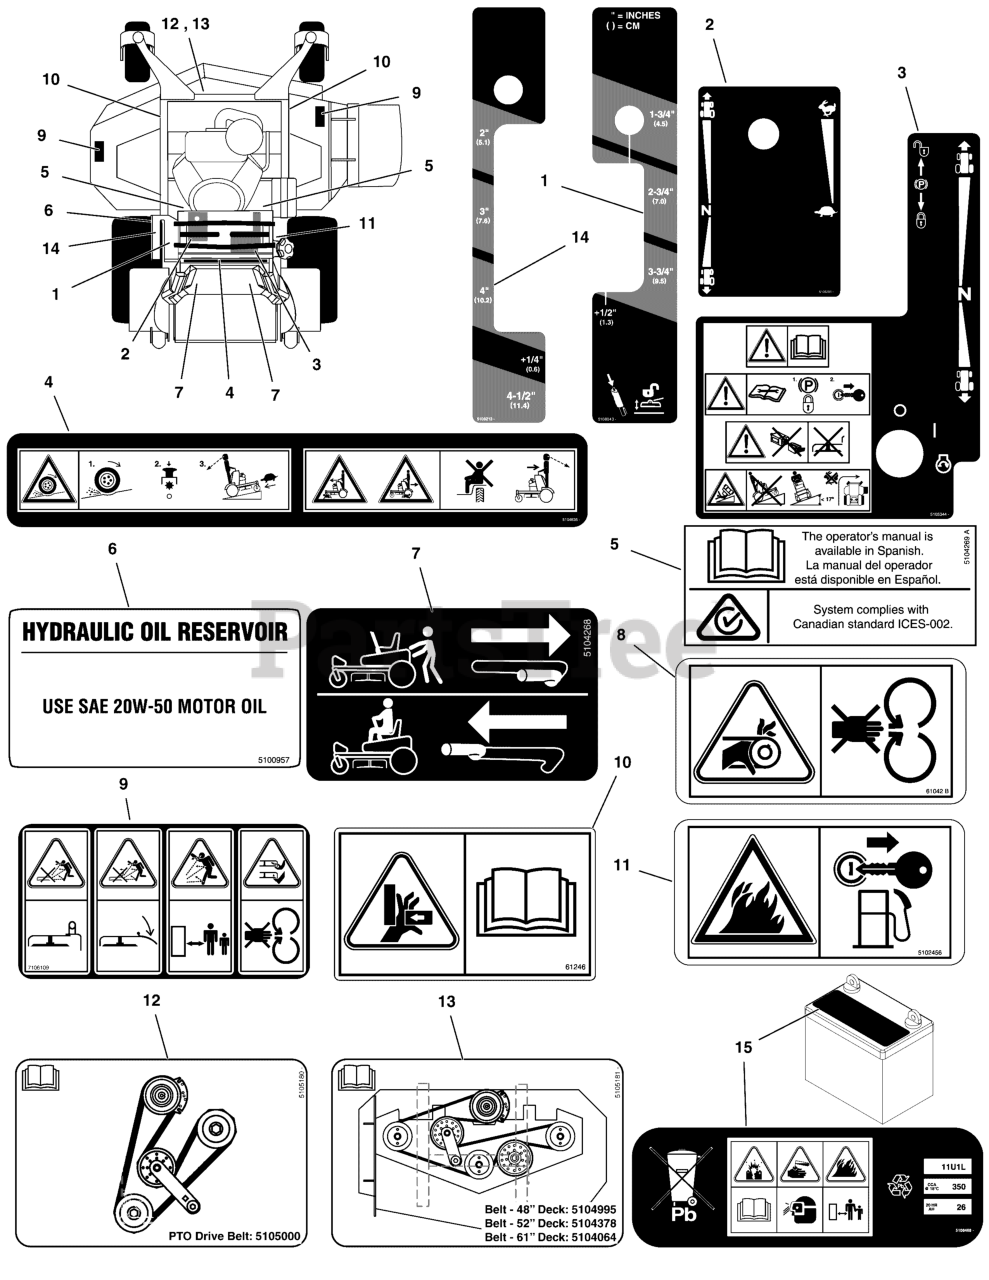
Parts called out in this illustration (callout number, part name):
1	DECAL, CUT HEIGHT, STAND ON, Z1 & SS100
2	DECAL, DASH PANEL, LH, CONTROLS
3	DECAL, DASH PANEL, RH, WRNGS/CNTRLS, CE
4	DECAL, WARNINGS, OPER COMPARTMENT, CE
5	DECAL, SPANISH MANUAL, IGES, C-TICK
6	DECAL, HYDRAULIC OIL, 20W-50, 1" X 1.44"
7	DECAL, TRANSAXLE RELEASE, WB
8	DECAL, CE DANGER, HAND IN BELT
9	DECAL, DISCHARGE SAFETY, EXPORT
10	DECAL, Pinch Point, CE
11	DECAL, FIRE ANSI EXPORT
12	DECAL, BELT ROUTING, SRS-36
13	DECAL, BELT ROUTING, SRS-48-52-61
14	DECAL, CUT HEIGHT, SRSZ1
15	DECAL, BATTERY, EXP, 11U1L
